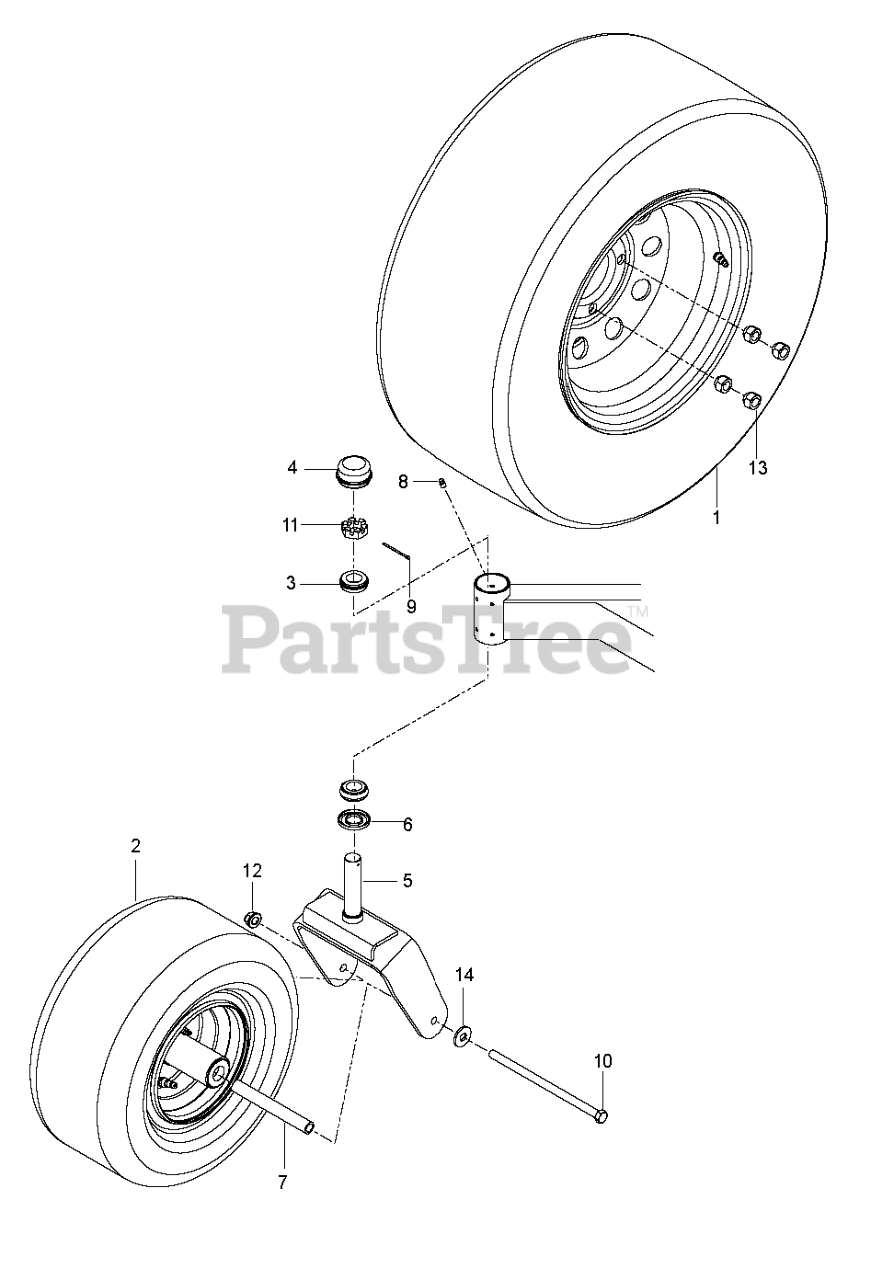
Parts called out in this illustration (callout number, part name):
1	WHEEL.ASM.23X10.50-12 1.375SLV
1	TIRE.23X10.5-12.K500.SERVICE
2	TIRE.ASSEM.CASTER.13X6.5-6.SIL
3	TAPERED ROLLER BRG
4	GREASE CAP
5	FORK.CASTER.ASM.PNT.668
7	SPACER, PIVOT
9	COTTER PIN 1/8 X 2
10	HEX SCREW 1/2-13 X 9.5 GR5
11	NUT 1"C HEX SLOTTED
12	NUT, 1/2-13 HEX FLG NYLOC ZD
13	LUG NUT 1/2F
14	WASH USS FLAT 1/2
